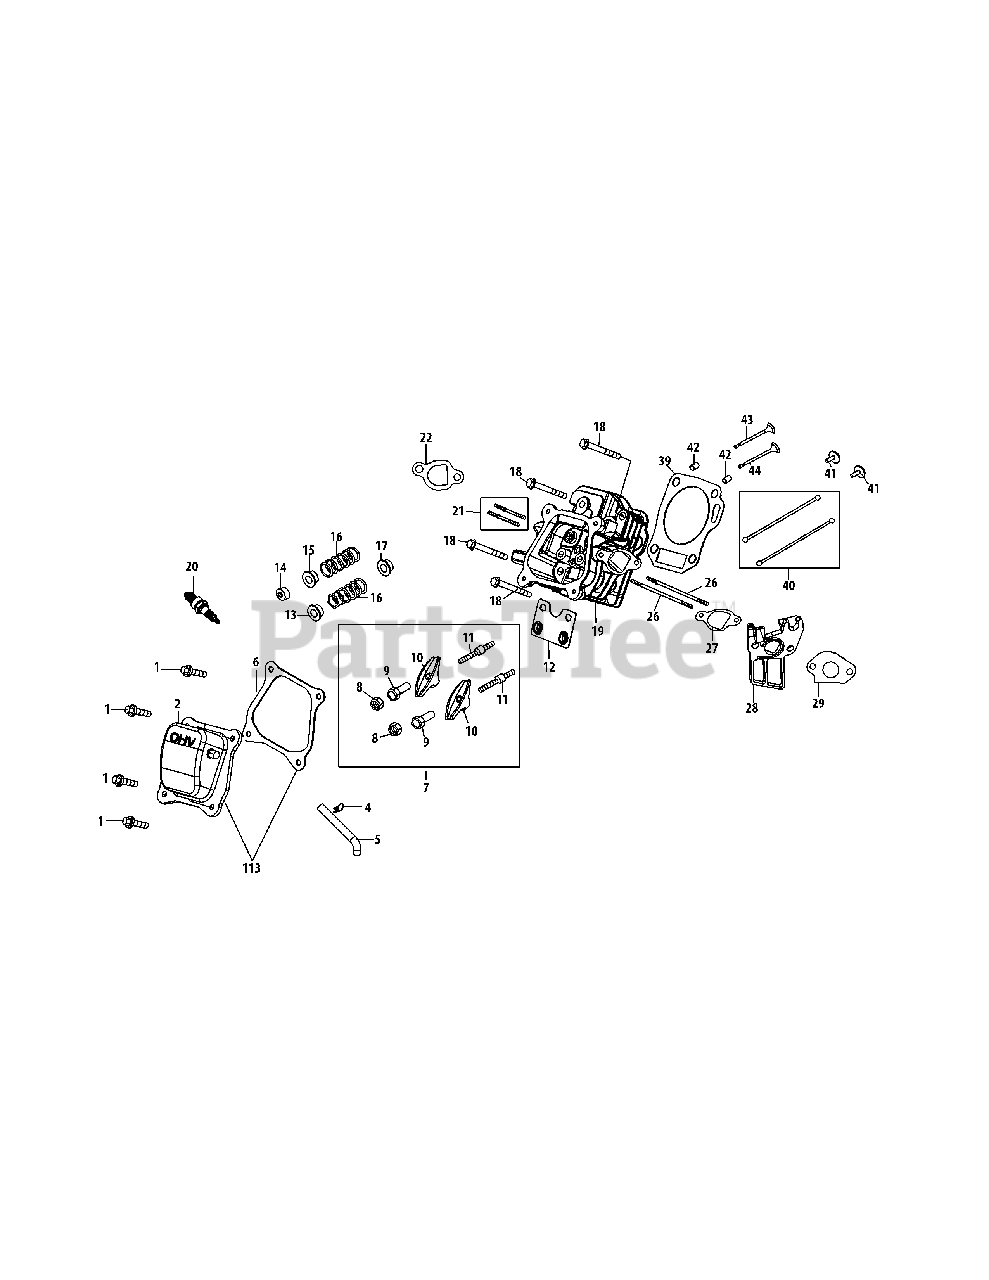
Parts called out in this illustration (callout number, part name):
1	Bolt M6×16
2	Valve Cover
4	Breather Hose Clamp
5	Breather Hose
6	Valve Cover Gasket
7	Rocker Arm Assembly
8	Nut, Pivot Locking
9	Adjusting Nut ,Valve
10	Rocker Arm
11	Bolt, Pivot
12	Push Rod Guide
13	Retainer, In.Valve Spring
14	Adjuster, Exh Valve
15	Retainer, Ex.Valve Spring
16	Valve Spring
17	Intake Valve Seal
18	Bolt M8×55
19	Cylinder Head Assembly
20	Spark Plug
21	Muffler Stud M8×36
21	Muffler Stud Assy
22	Muffler Gasket
26	Carb Stud M6×110
27	Carburetor Insulator Gasket
28	Carburetor Insulator Plate
29	Carburetor Gasket
39	Gasket, Cylinder Head
40	Push Rod Kit
42	Dowel Pin 10×16
43	Valve Kit
113	Valve Cover Kit
